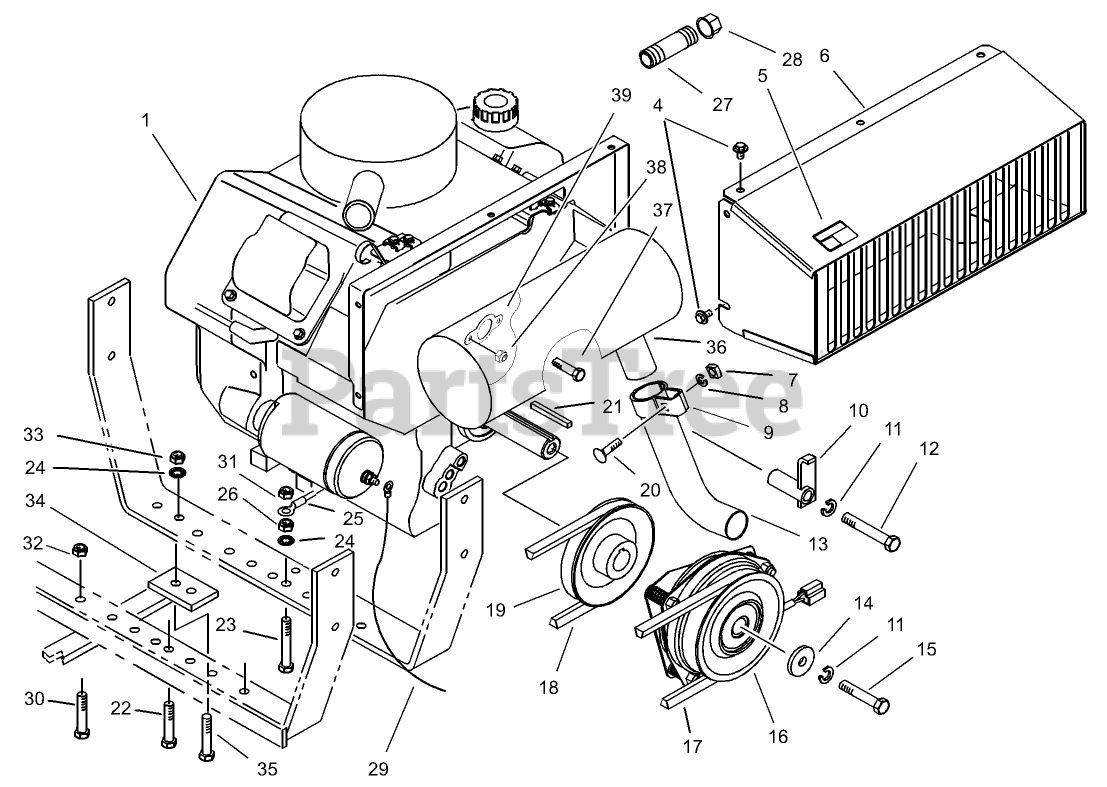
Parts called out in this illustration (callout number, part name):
1	Engine-Kohler 20 HP Model CH20QS-64678
4	SCREW
5	DECAL-WARNING
6	Duct-Engine
7	NUT-HEX
8	WASHER-LOCK
9	Clamp Assembly (Incl. Ref. #7, 8 & 20)
10	Anchor Bracket
11	WASHER-LOCK
12	SCREW-HH
13	EXHAUST PIPE
14	WASHER-CLUTCH
15	SCREW-HH
16	BRAKE CLUTCH ASM
17	V-BELT, JACKSHAFT
18	V-BELT, TRACTION
19	ENGINE PULLEY
20	SCREW-CARR
22	SCREW-HH
23	SCREW-HH
24	WASHER-LOCK, INTERNAL
25	WIRE ASM (NEGATIVE)
26	NUT-LOCK, NI
27	NIPPLE
28	CAP-PIPE
29	POSITIVE WIRE ASM
30	SCREW-HH
31	NUT-HHF, WHIZ
32	NUT-HF
33	WASHER-FLAT
34	Guard-Tank
35	SCREW-HH
36	Muffler
37	SCREW-HHF
38	Nut-Lock
39	GASKET-EXHAUST
